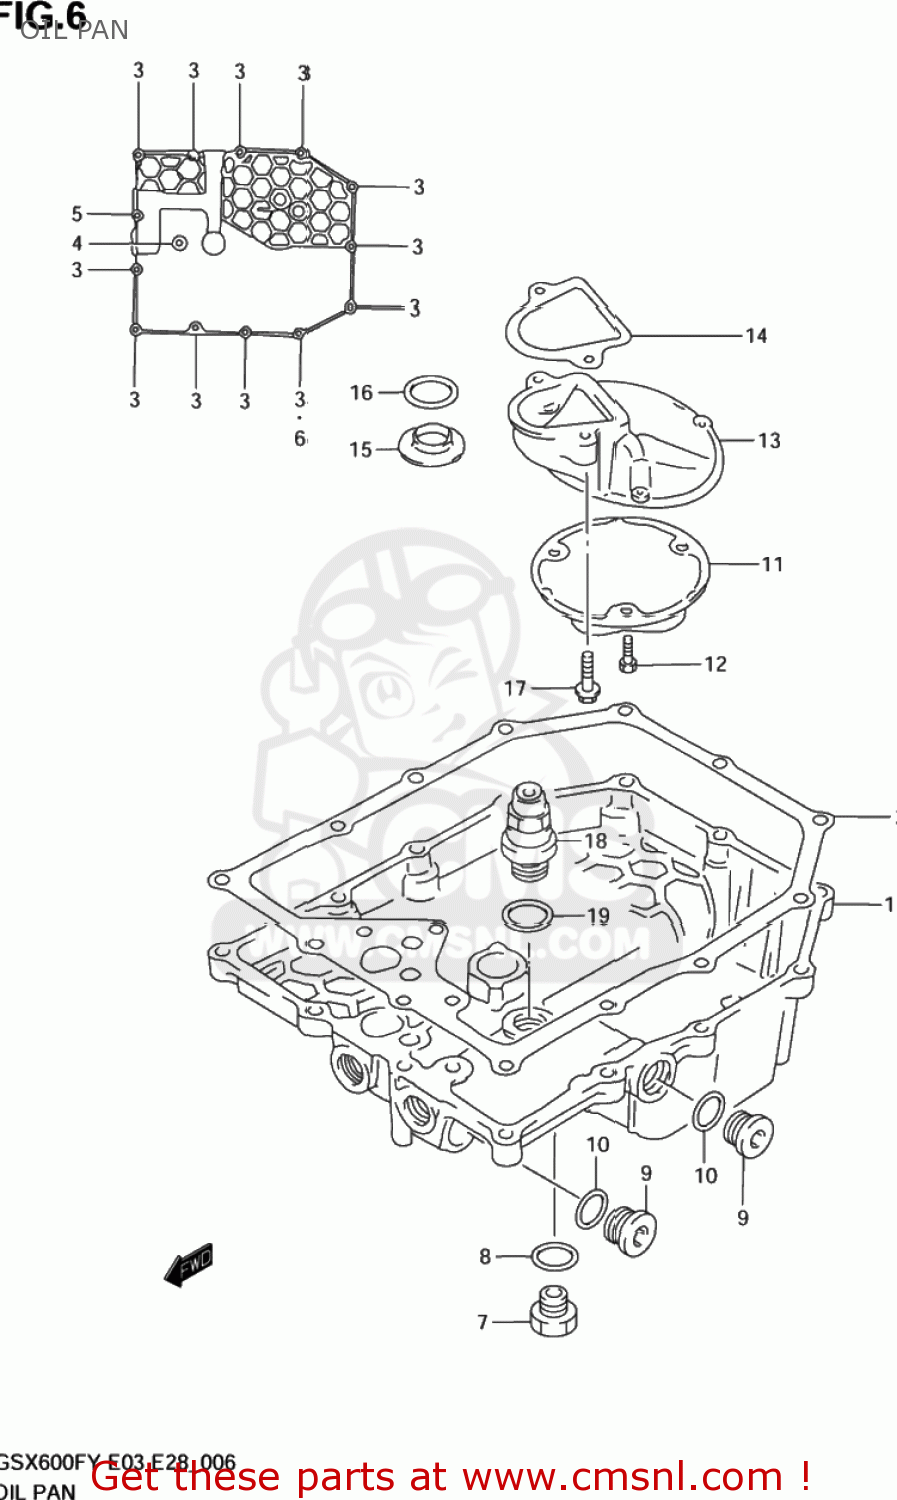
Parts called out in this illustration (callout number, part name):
1	PAN,OIL
2	GASKET,OIL PAN(ASB) (NAS)
3	BOLT
4	BOLT
5	BOLT
6	GASKET(5.8X11X1.2) (NAS)
7	PLUG
8	GASKET(13.8X18.8X4.8) (NAS)
9	PLUG,16X8
10	GASKET(16X22X2) (NAS)
11	STRAINER,ENGINE OIL
12	BOLT
13	PROTECTOR,OIL STRAINER
14	GASKET,OIL STRAINER PROTECTOR (NAS)
15	GASKET,OIL OUTLET (NAS)
16	O RING(D:3.2,ID:17.8)
17	BOLT
18	VALVE ASSEMBLY,OIL RELIEF
19	GASKET(16X22X2) (NAS)
